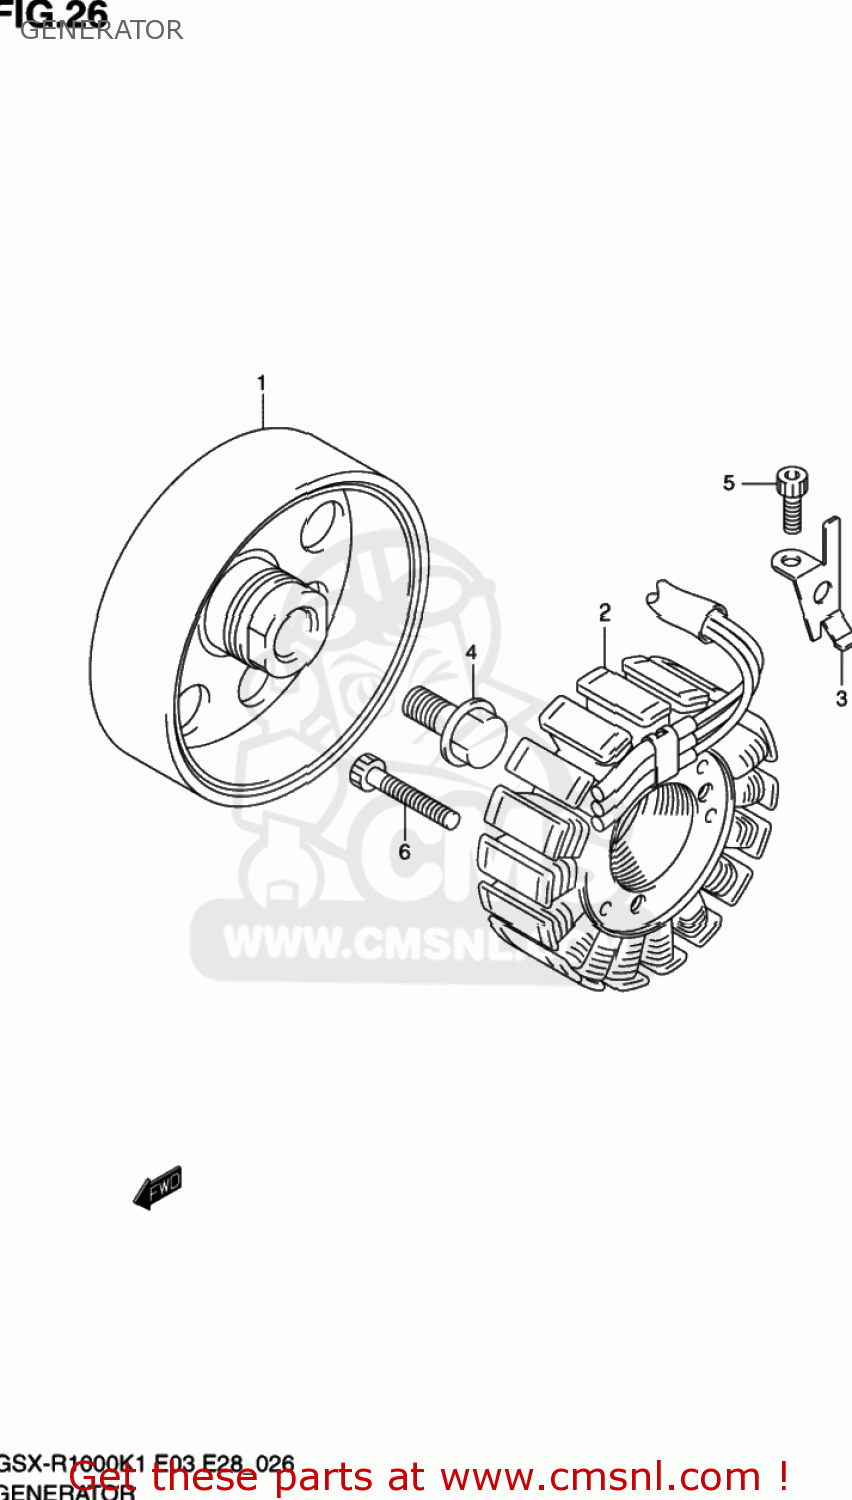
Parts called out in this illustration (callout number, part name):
1	ROTOR ASSY
2	STATOR ASSY
3	CLAMP,MAGNETO LEAD
4	BOLT(12X23)
5	BOLT,STRANGER
6	BOLT
